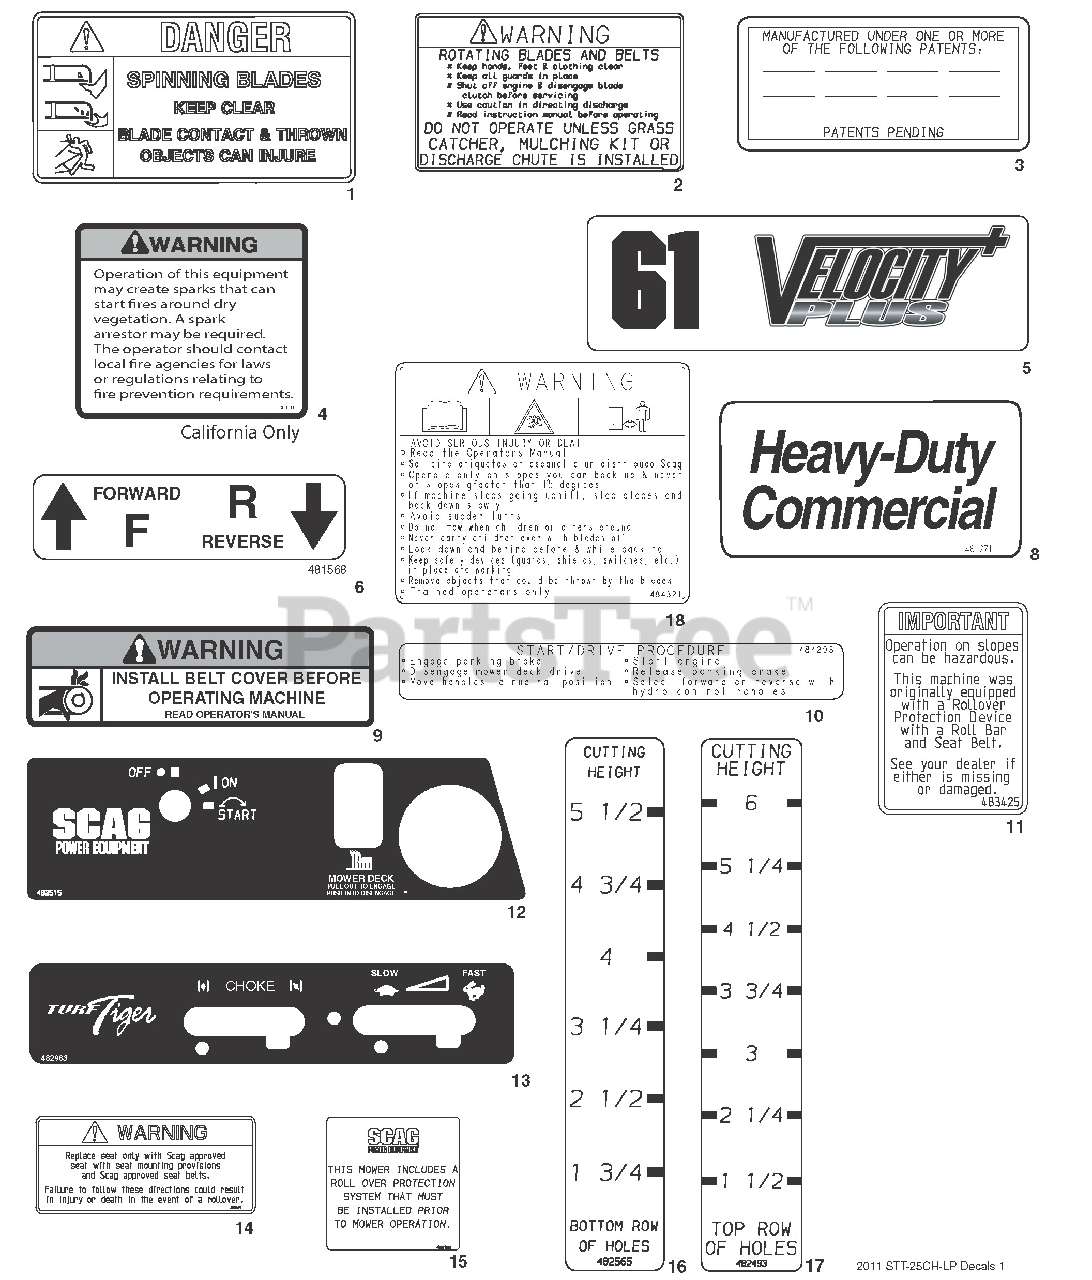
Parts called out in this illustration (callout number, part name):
1	Decal, Danger-Spinning Blades
2	Decal, Warning-Rotating Blades
3	Decal, Patents
4	Decal, Warning Spark Arrestor
5	Decal, 52" Velocity Plus
5	Decal, 61" Velocity Plus
6	Decal, Traction Control
8	Decal, Heavy Duty Commercial
9	Decal, Belt Cover
10	Decal, Start / Drive
11	Decal, ROPS
12	Decal, Instrument Panel - Upper
13	Decal, Instrument Panel - Lower
14	Decal, Seat Replacement
15	Decal, ROPS
16	Decal, Cutting Height - Lower
17	Decal, Cutting Height - Upper
18	Decal, Start/Drive Procedure
